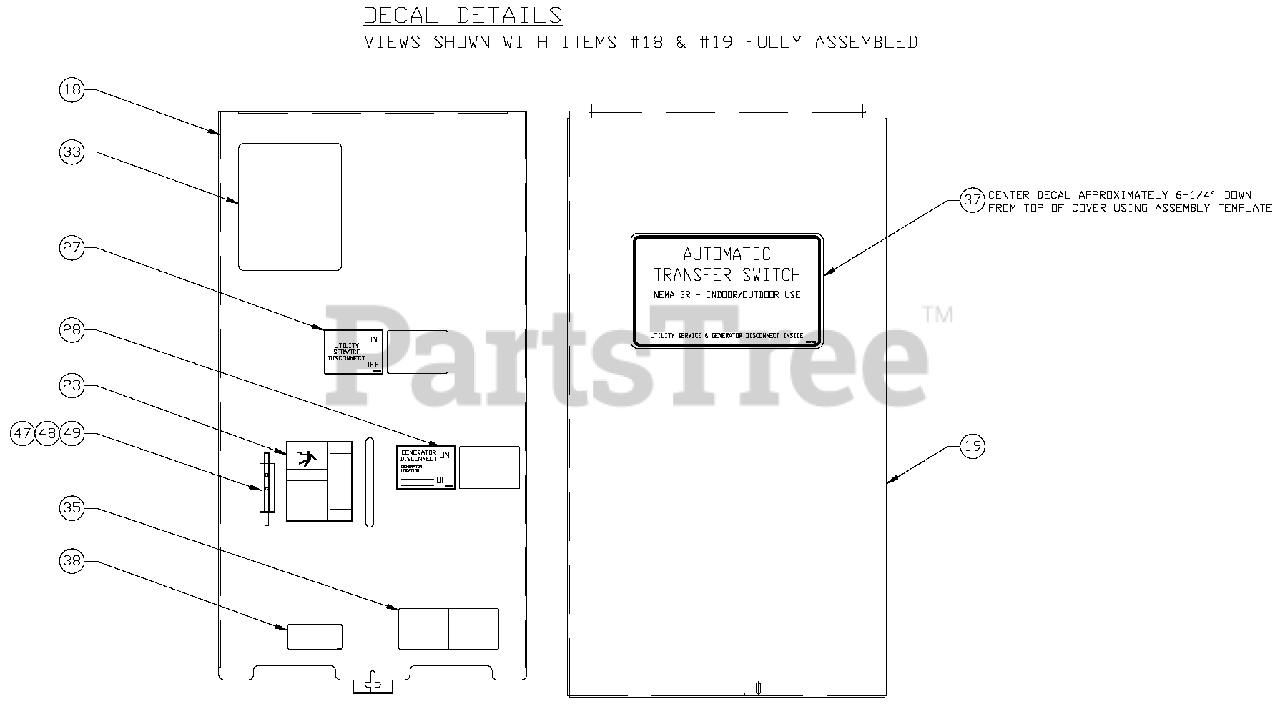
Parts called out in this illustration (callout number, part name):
18	COVER, INSIDE 200A DUAL BREAKER
19	COVER, TRANSFER SWITCH
23	DECAL, MANUAL OPERATING HANDLE
24	DECAL, UTILITY SOURCE CONN
27	DECAL, UTILITY DISCONNECT
28	DECAL, GENERATOR DISCONNECT
33	DECAL, TEST SEQUENCE
35	DECAL, TERMINAL SHOCK HZD BI
37	DECAL, FRNT CVR ATS 3R SER DIS
38	DECAL LIVE CIRCUIT ENG/FRN/SPN
47	BRACKET, ARM EXTENDER
48	RIVET POP .156 X .362 AL
49	ARM EXTENDER PIN
